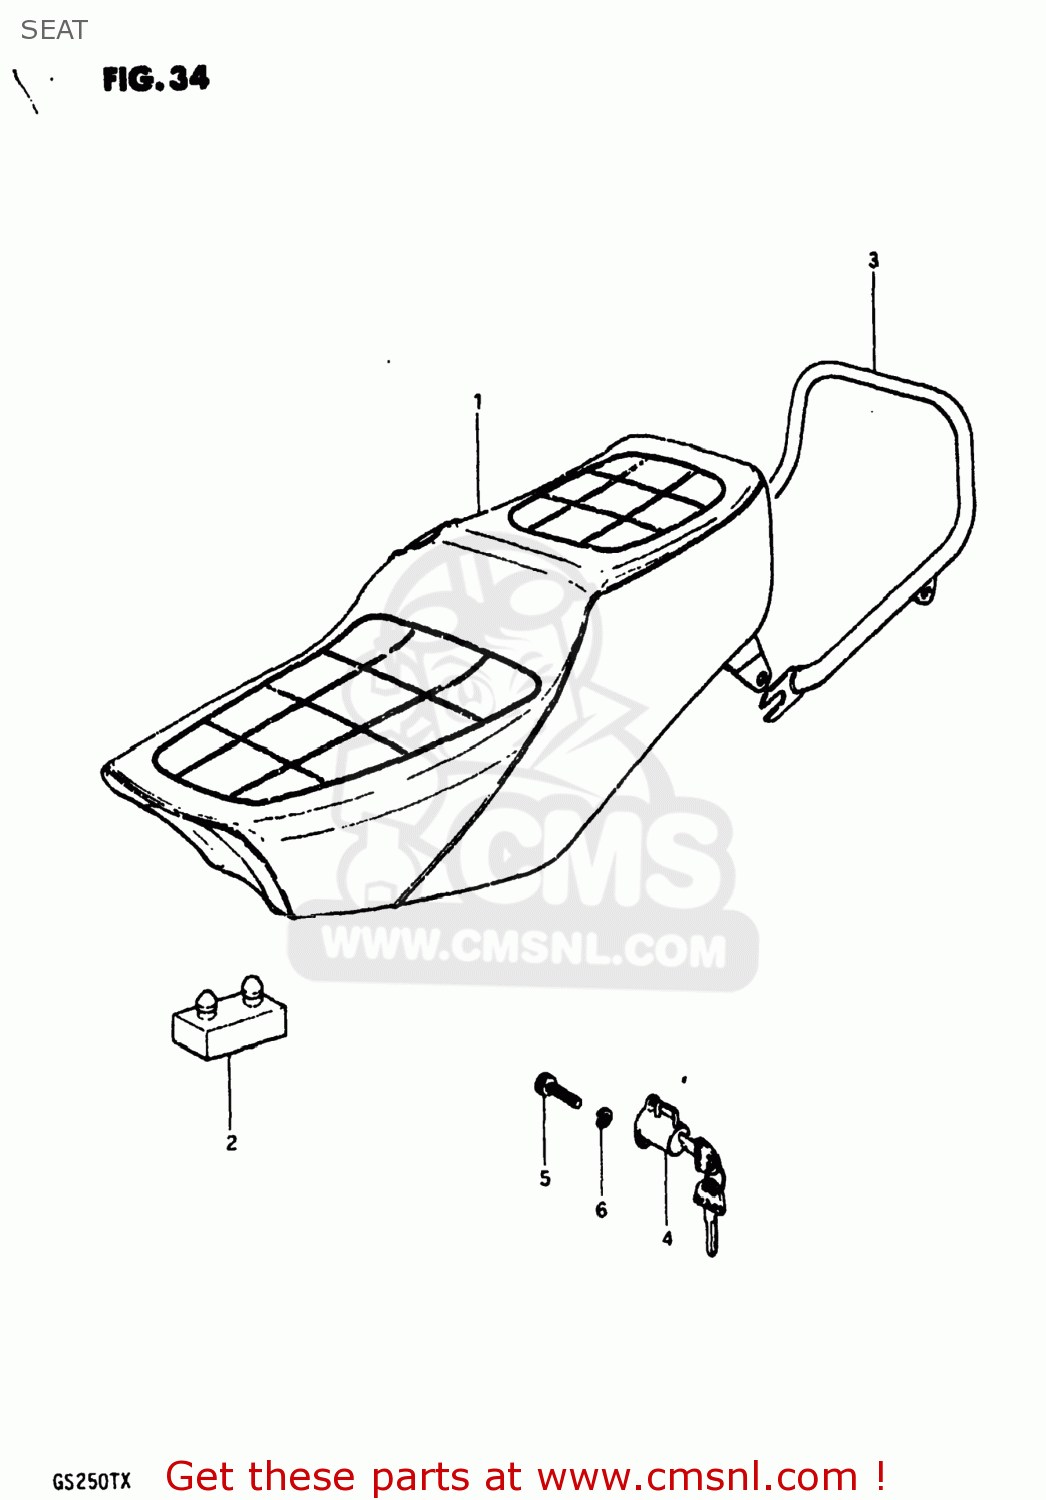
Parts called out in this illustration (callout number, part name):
1	SEAT ASSEMBLY
2	CUSHION
3	HANDLE,PILLION RIDER
4	LOCK ASSEMBLY,HELMET
5	BOLT 6X11
6	LOCK WASHER
